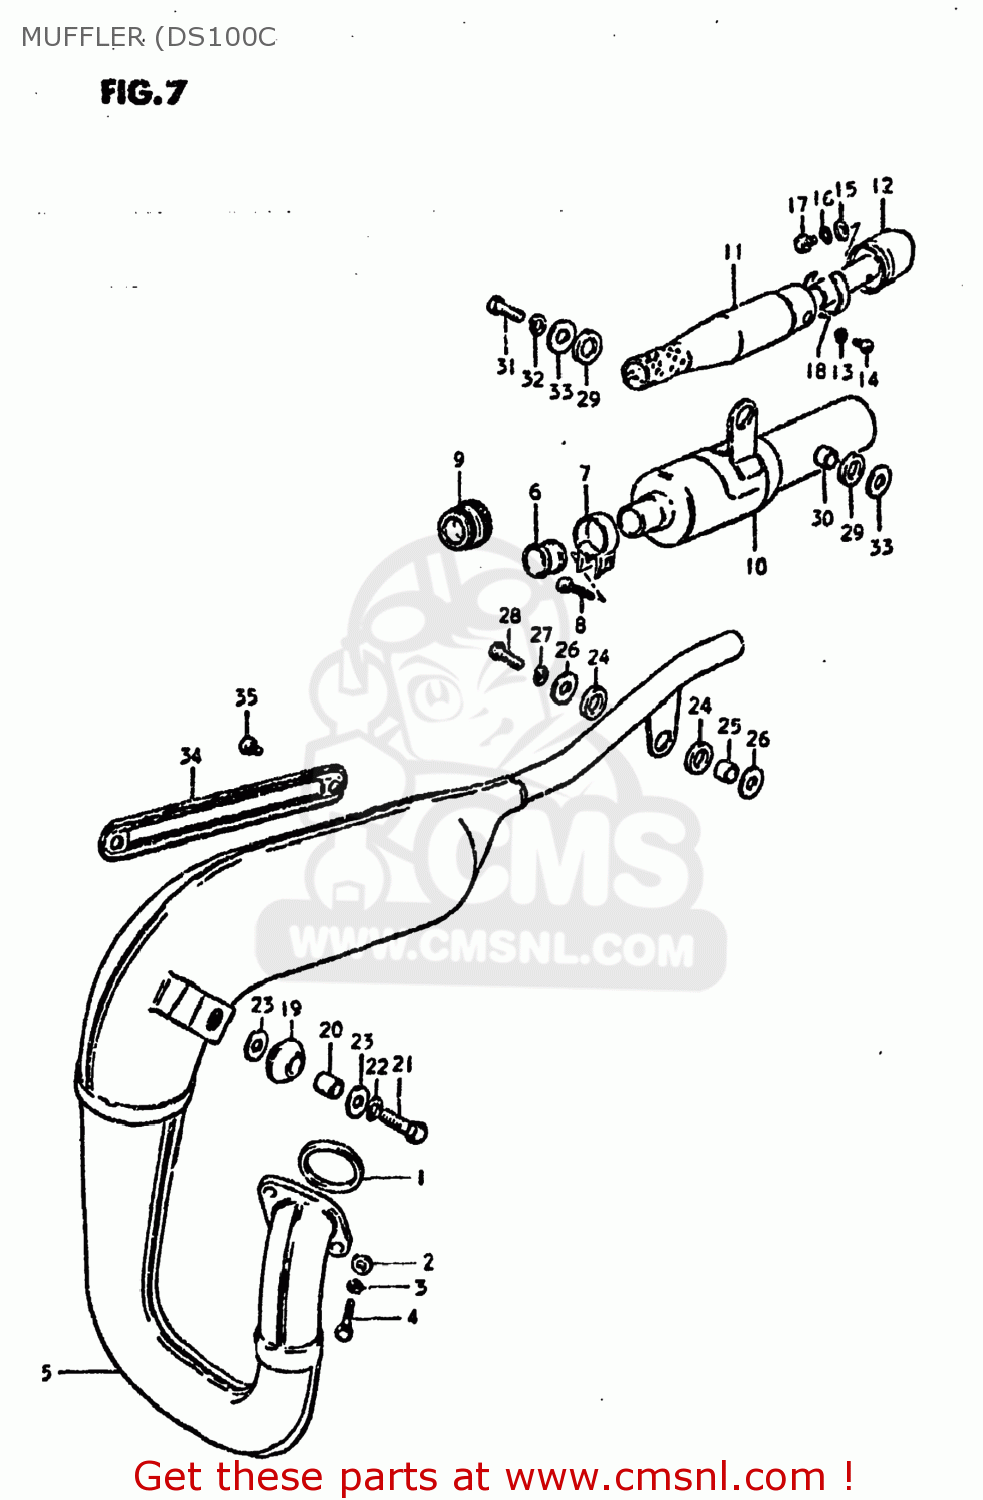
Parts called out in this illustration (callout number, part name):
1	GASKET,EXHAUST PIPE (NAS)
2	WASHER
3	LOCK WASHER
4	SCREW
5	BODY,MUFFLER
6	CONNECTOR,MUFFLER
7	CLAMP
8	SCREW
9	CONNECTOR,MUFFLER
10	MUFFLER ASSEMBLY
11	ARRESTER,SPARK
12	TUBE,MUFFLER CLEAN OUT
13	LOCK WASHER
14	SCREW
15	WASHER
16	LOCK WASHER
17	SCREW(6X8)
18	BAND,SPARK ARRESTER
19	DAMPER,MUFFLER,FR
20	SPACER (8X12X15)
21	BOLT
22	LOCK WASHER
23	WASHER (8.7X22X2)
24	CUSHION
25	SPACER (8.6X13.8X9.8)
26	WASHER
27	LOCK WASHER
28	BOLT
29	CUSHION
30	SPACER (8.6X13.8X9)
31	BOLT
32	LOCK WASHER
33	WASHER
34	COVER,MUFFLER
35	SCREW.M6X1X8
